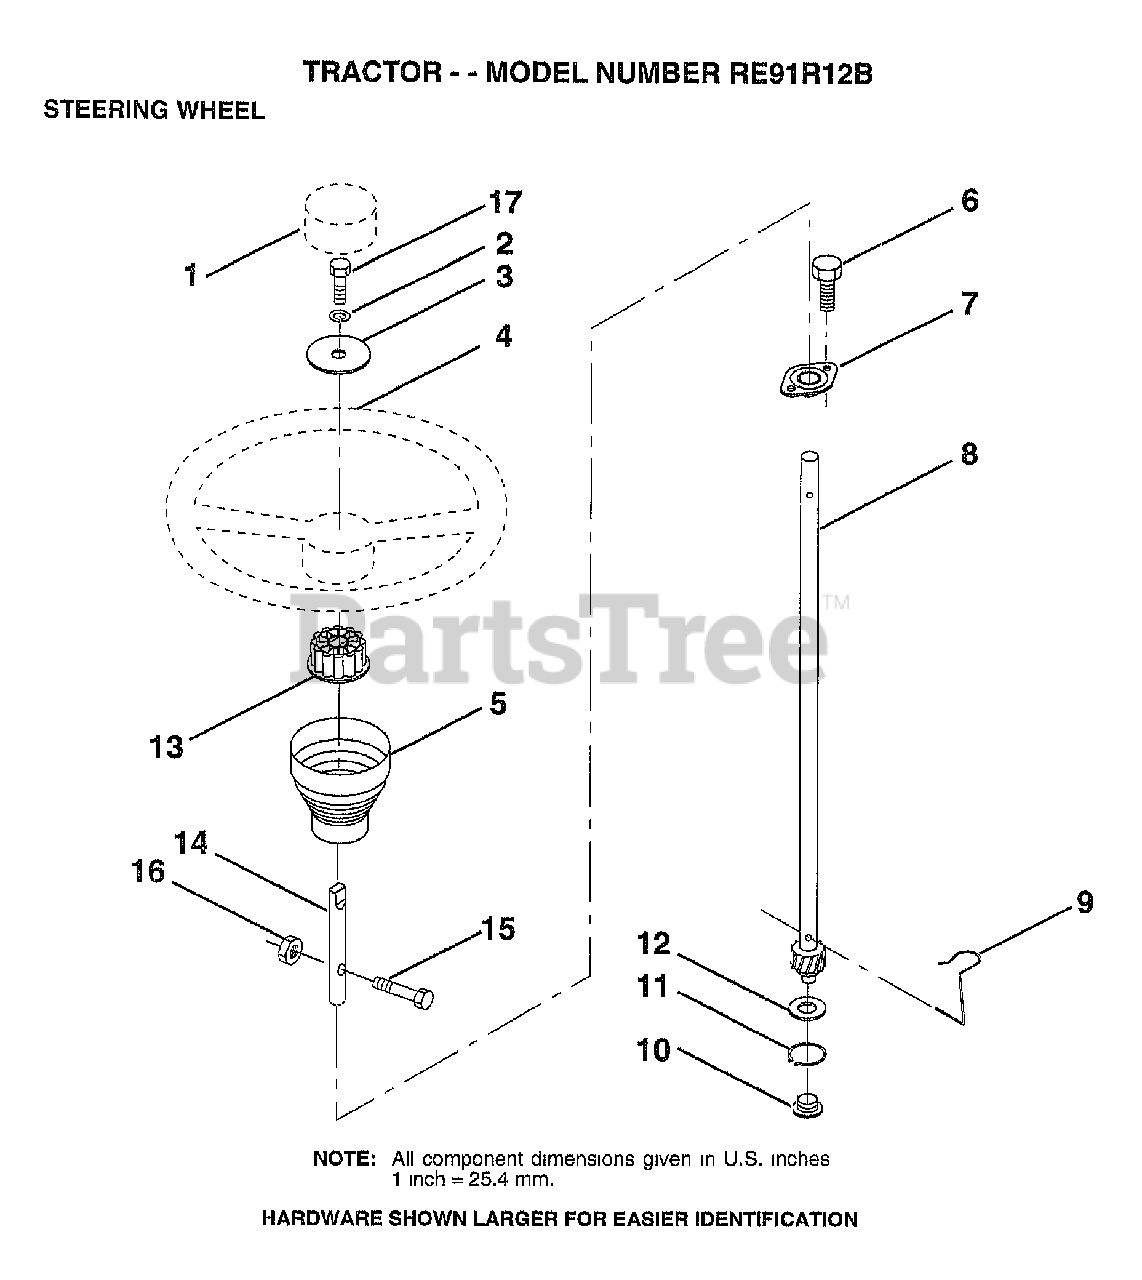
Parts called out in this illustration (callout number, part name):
1	ST WHL INSERT CAP
2	LOCKWASHER
3	WASHER T
5	SLEEVE STEERING
6	"SCREW-TT,10-32 FL"
7	BUSHING.STR.623
8	SHAFT.STEERING.LR
9	STEERING CLIP
10	BUSHING STEER LWR
11	RING
12	WASHER LT
13	ADAPTER LT
14	EXT SHAFT STEERIN
15	BOLT
16	NUT
17	BOLT
